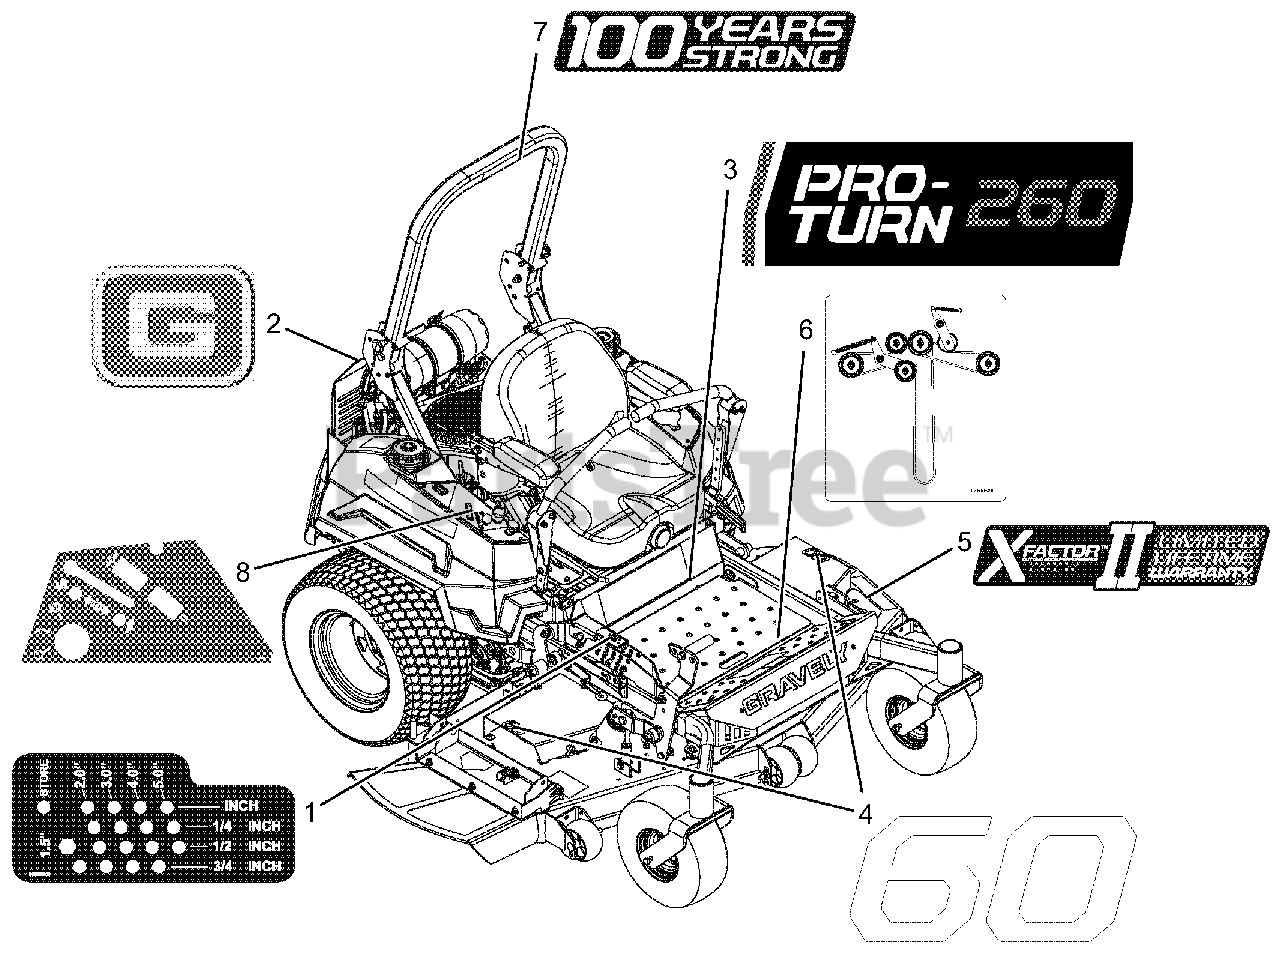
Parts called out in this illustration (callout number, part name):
1	DECAL, HEIGHT OF CUT
2	DECAL, GRAVELY BRAND
3	DECAL, PRO-TURN 260
4	DECAL, 60"
5	DECAL, X-FACTOR DECK
6	DCL,BELT ROUTE-RH BK-SIDE IDLR
7	DECAL, GRAVELY 100 YR
8	DECAL, EFI CONTROL PANEL
